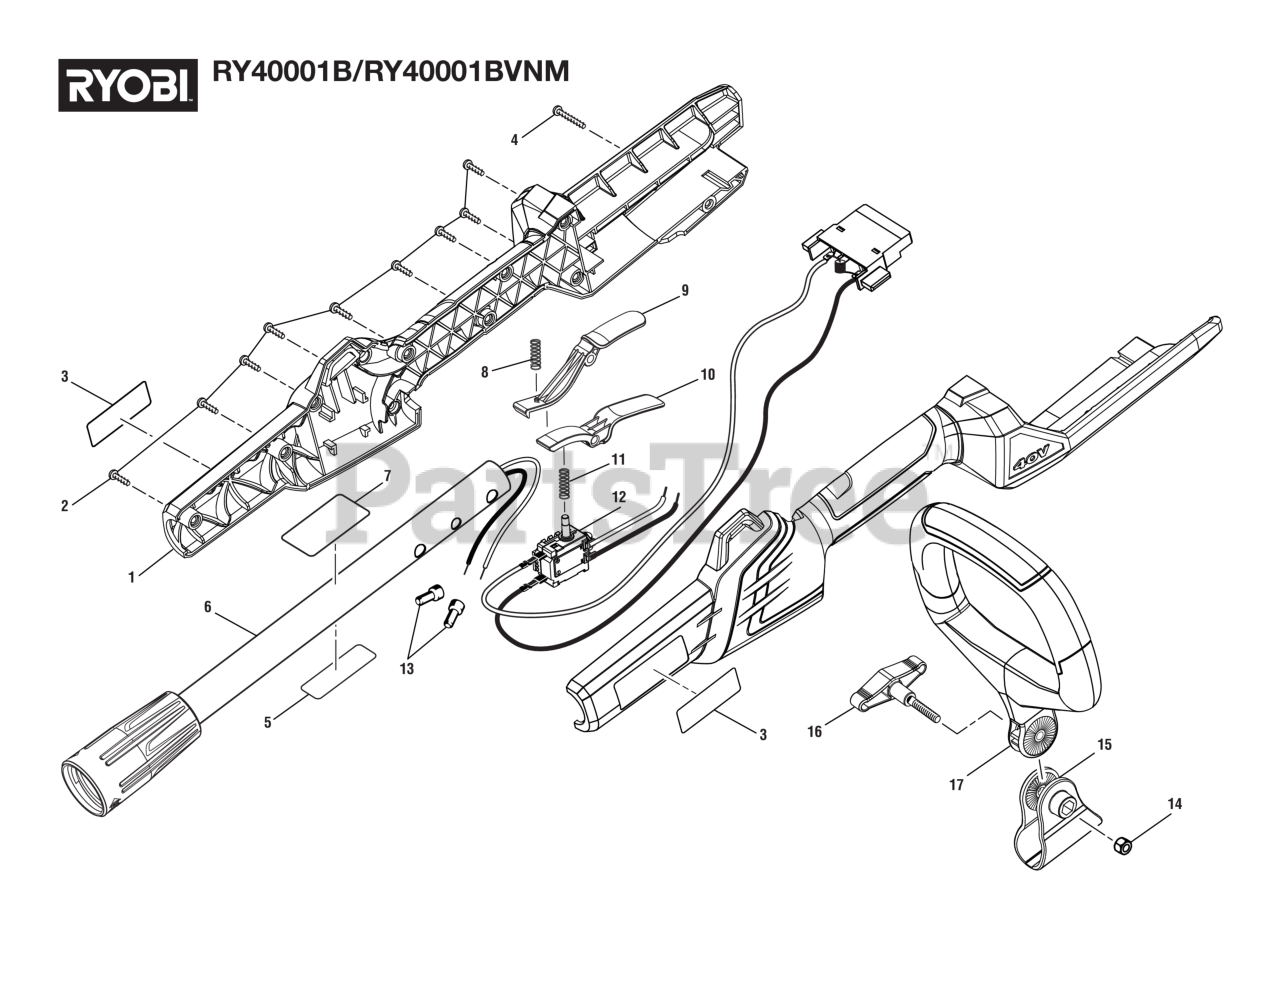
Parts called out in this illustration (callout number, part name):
1	Rear Handle Assembly (Inc. Key No. 3)
2	Screw (M4 x 14 mm, T15 Torx Pan Hd.))
3	Logo Label
4	Screw (M4-18 x 30 mm, T15 Torx Soc. Hd.)
5	Data Label
6	Upper Tube Assembly
7	Warning Icon Label
8	Compression Spring (Trigger)
9	Lock Off Button (Trigger Lock)
10	Switch Trigger
11	Compression Spring (Trigger)
12	Switch and Contact Plate Assembly.
13	Wire Connector (Closed End)
14	Lock Nut (M6)
15	Clamp Assembly
16	Handle Knob Assembly
17	Auxiliary Handle Assembly
